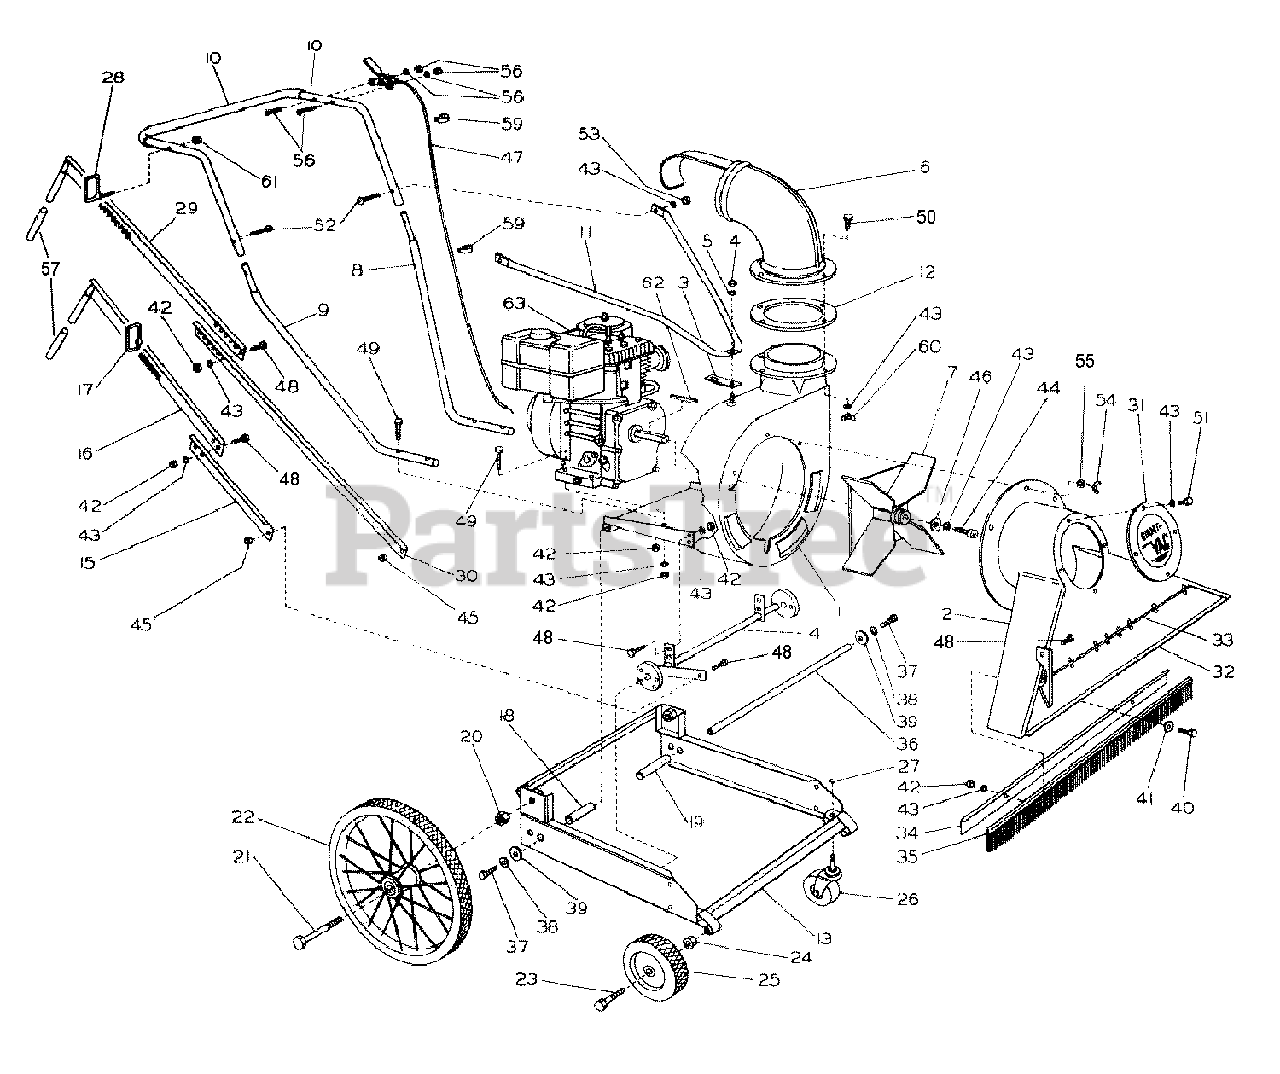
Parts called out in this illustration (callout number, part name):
1	Blower housing & engine base
2	30F nose cone body
2	36F nose cone body
2	30C nose cone body
2	36C nose cone body
3	Anti-vibration bracket
4	Nut, 3/8’ hex
5	Washer, 3/8 lock
6	Exhaust elbow
7	Impeller (complete w/Taper-Lok hub #46)
8	Lower handle left
9	Lower handle right
10	Upper handle
10	Foam handle cover
11	Handle brace
12	Rubber gasket
13	Under carriage
14	Lifter cam
15	Lower lifter arm
16	Upper lifter arm
17	Lifter arm U clip
18	Spacer back wheel - right
19	Spacer back wheel - left
20	Nut, 3/4 hex
21	Bolt, 3/4 x 5 hex
22	Wheel, 20 - Rear
23	Bolt, 1/2-13 x 2-1/2 hex
24	Nut, 1/2-13 hex
25	Wheel, 8 x 1.75 - Front
26	4 caster wheel – plain stem
27	Snap clip – comes with 4 caster
28	U type holder
29	Upper adjuster bar
30	Lower adjuster bar
31	Cover plate
32	Door for 30F
32	Door for 36F
33	Hinge for 30F
33	Hinge for 36F
34	Brush holder 30
34	Brush holder 36
36	22 lift pivot axle
37	Bolt, 1/2 x 1 hex
38	Washer, 1/2 lock
39	Washer, 1/2 flat
40	Bolt, 5/16 x 1 1/4 hex
41	Washer, 5/16 flat
42	Nut, 5/16 hex
43	Washer, 5/16 lock
44	Bolt, 5/16-18 x 1-1/4 hex Gr 5
45	Nut, 5/16 lock
46	Taper-Lok hub – 1-1/8
47	Throttle control
48	Bolt, 5/16 x 3/4 hex
49	Bolt, 5/16 x 1 3/4 hex
50	Bolt, 5/16 x 1 hex
51	Bolt, 5/16 x 5/8 hex
52	Bolt, 5/16 x 1 1/2 round head
53	Nut, 5/16 acorn
54	Bolt, 3/8-16 wing
55	3/8 lock washer
56	Kit, 10-24 x 1 1/4 bolt/washer/nut
57	Handle grip
59	Throttle clip
60	Nut, 5/16 wing
61	Nut, 1/4 lock
62	1/4 x 2-1/8 impeller key
63	* Engine, 9 HP B&S Intek
